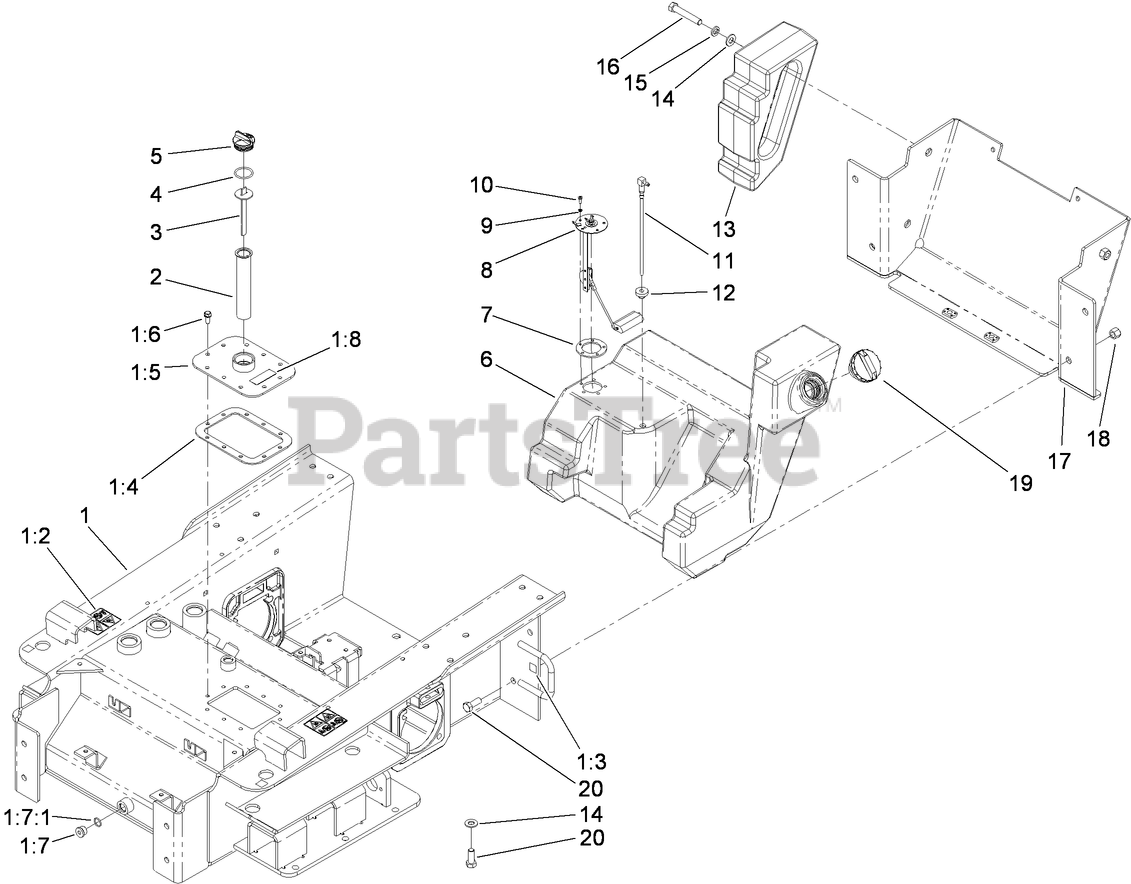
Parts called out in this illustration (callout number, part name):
1	CHASSIS ASM
1:2	DECAL-WARNING
1:3	DECAL-POINT, LIFT
1:4	GASKET-COVER, ACCESS
1:5	TANK COVER ASM
1:6	SCREW
1:7	PLUG-HEX
1:7:1	O-RING
1:8	DECAL-OIL, HYD
2	FILTER-SCREEN
3	DIPSTICK-OIL
4	O-RING
5	PLUG-PLASTIC
6	TANK-FUEL
7	GASKET-SENDER, FUEL
8	SENDER-FUEL
9	WASHER-LOCK
10	SCREW-PPH
11	PIPE-STAND
12	BUSHING
13	COUNTERWEIGHT-REAR
14	WASHER-FLAT
15	WASHER-LOCK
16	SCREW-HH
17	COVER-REAR
18	NUT-LOCK, NI
19	CAP-FUEL
20	SCREW-HH
